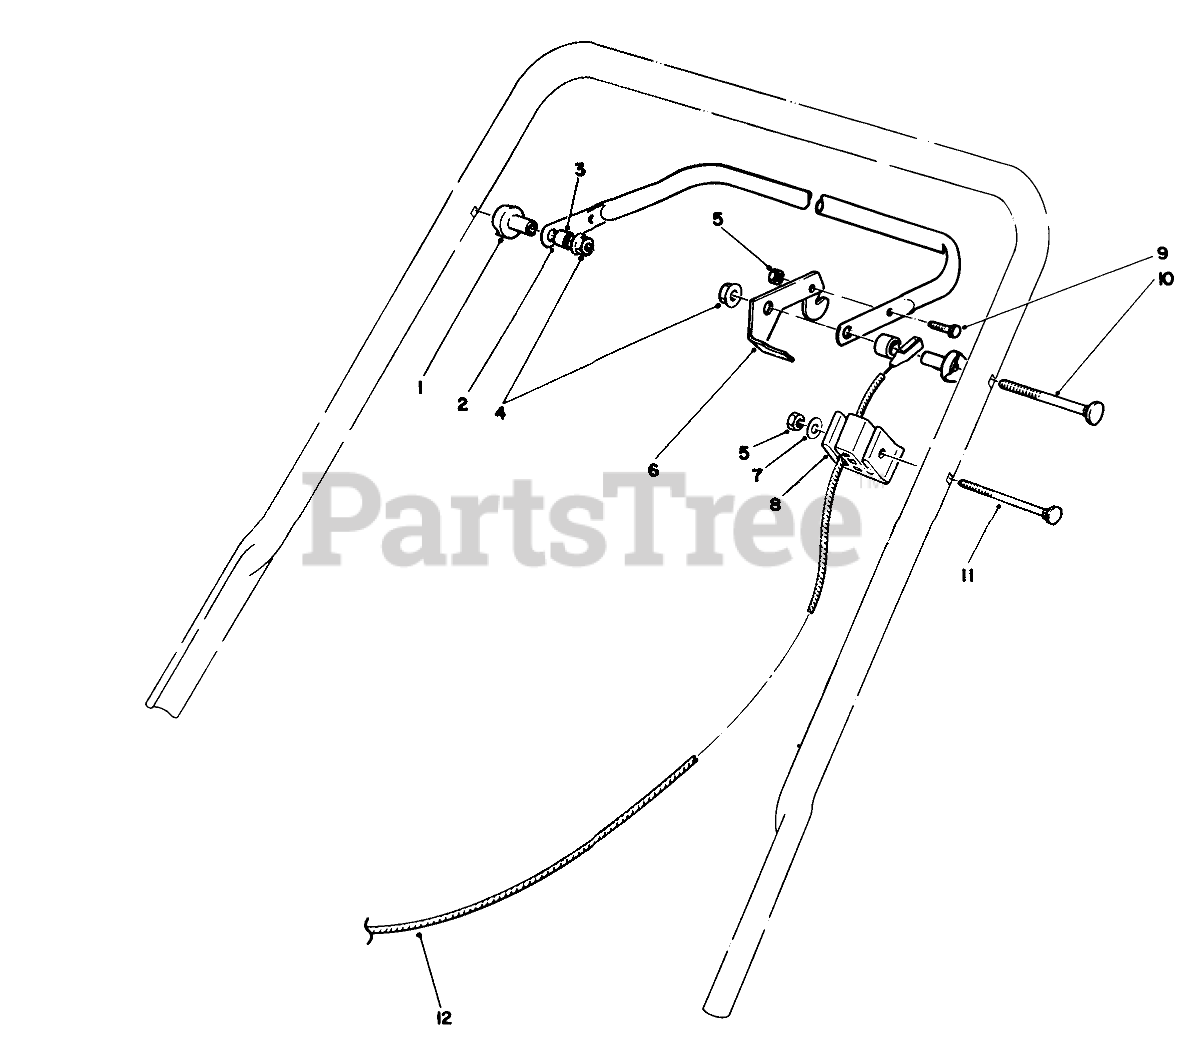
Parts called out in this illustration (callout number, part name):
1	SPACER-SUPPORT
2	Bar-Control
3	SPACER-NYLON
4	NUT-LOCK, NI
5	NUT-LOCK, NI
6	LEVER-CONTROL
7	WASHER-FLAT
8	SUPPORT-CABLE
9	SCREW-HH
10	5/16-18 X 2 HNDLE SCREW
11	HANDLE SCREW
12	BRAKE CABLE
